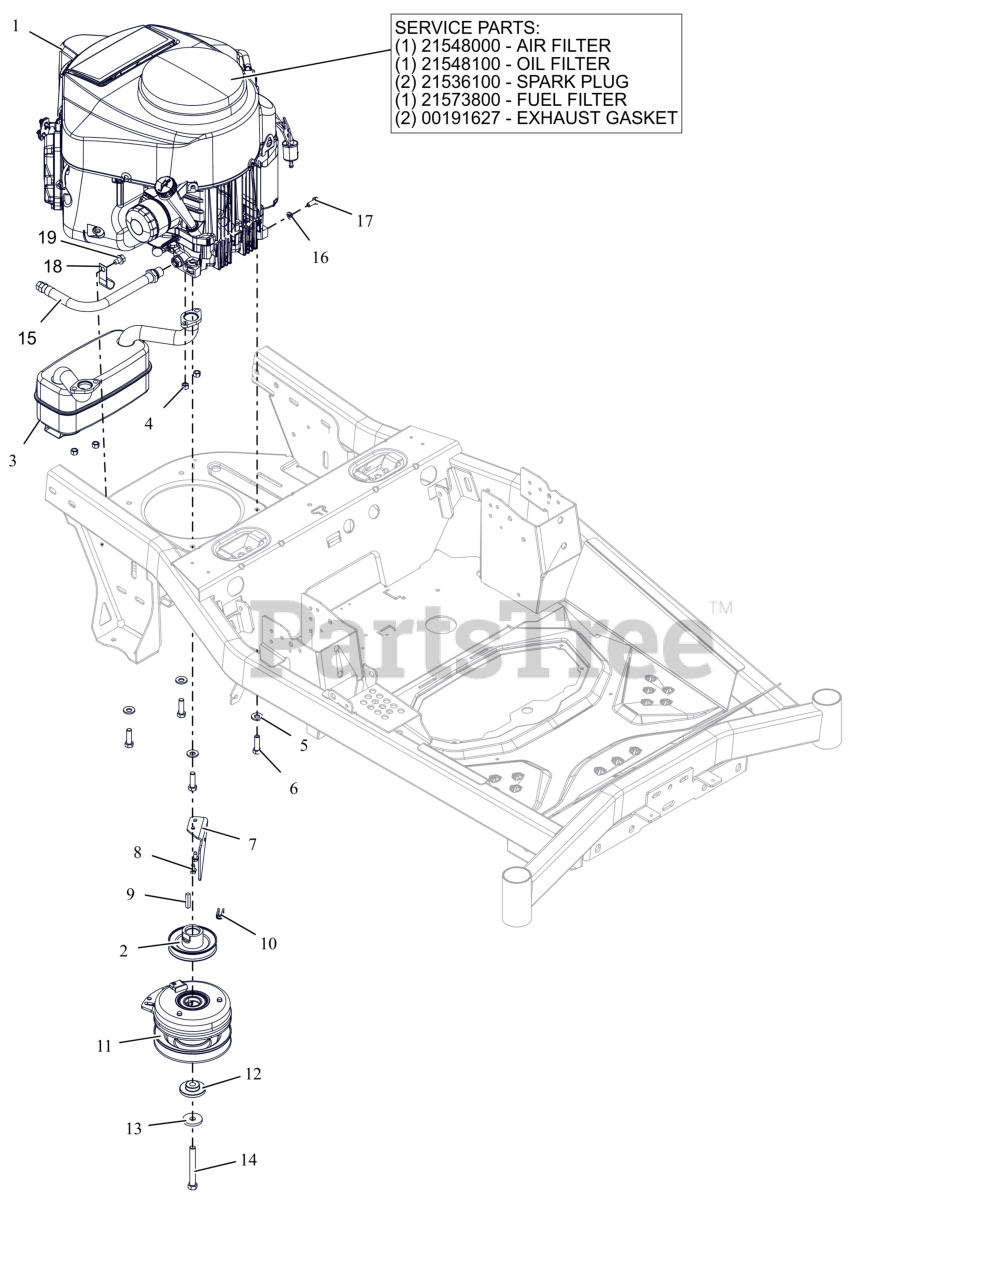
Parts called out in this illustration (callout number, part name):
1	ENGINE, KAWASAKI FR691 23HP
2	WLDMT-PULLEY-4.831OD X1.003
3	MUFFLER - KAWASAKI
4	NUT-LK-TOP-FLG M8 ZCC
5	WASHER, 3/8" SPRING DISC
6	BLT, HEX .38-16X1.25 G5 ZCC NT
7	BRKT- CLUTCH STOP
8	SCR-TAP .25-20X.50 HWH ZCC
9	KEY-SQ .25 X 1.25 X .25 SAE
10	BSHG, CLUTCH
11	CLUTCH, WARNER-IXR-18211
12	BSHG-FLG .469X1.06X.574X2.0
13	WASHER, 7/16" SPRING DISK
14	BLT- HEX .44-20X3.50 G8 ZCC NT
15	HOSE, OIL DRAIN
16	WSHR,LK-REG .312X.078 ZCC
17	BLT, HEX M8-1.25X20 G8.8 ZCC
19	SCR,TAP .375-16X.50 HWH TR ZCC
